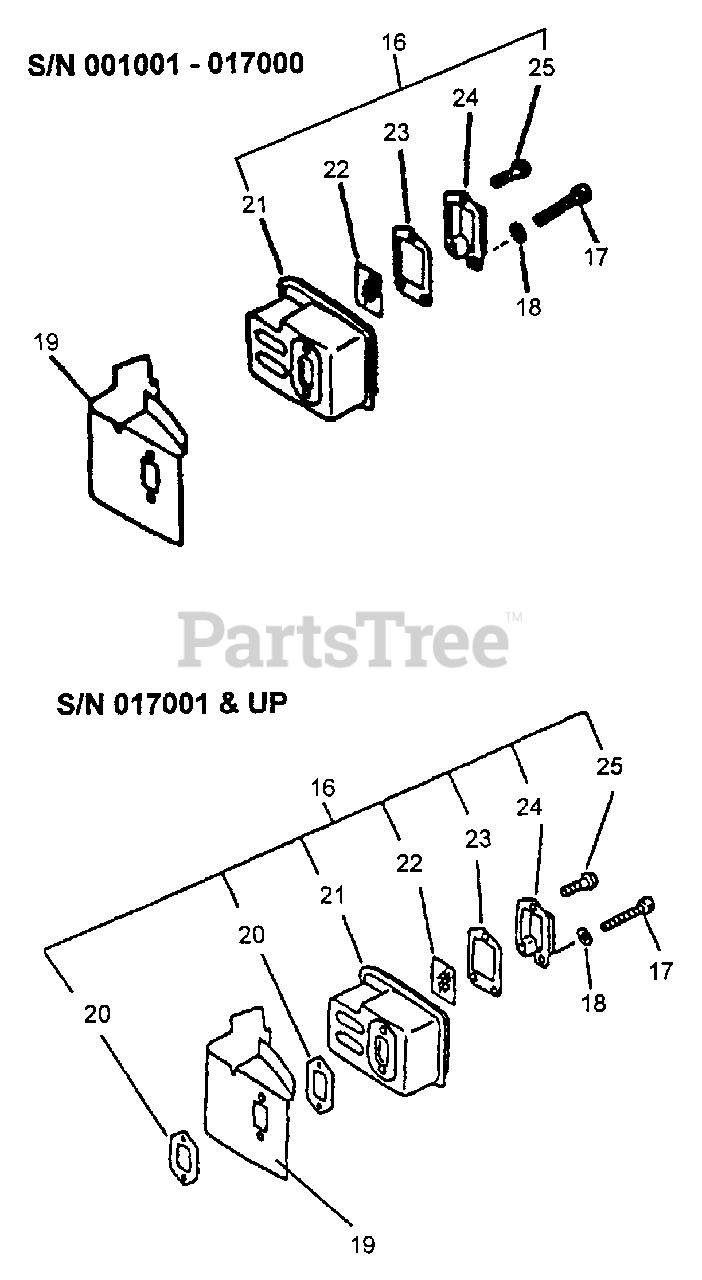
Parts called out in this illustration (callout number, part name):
16	MUFFLER ASSY
17	BOLT M5×50
18	WASHER, FLAT 5.5×10×0.8
19	COVER, MUFFLER
20	GASKET, EXHAUST
22	SCREEN, SPARK ARRESTER
23	GASKET, EXHAUST
24	GUIDE, EXHAUST - INNER
25	SCREW 4×10
